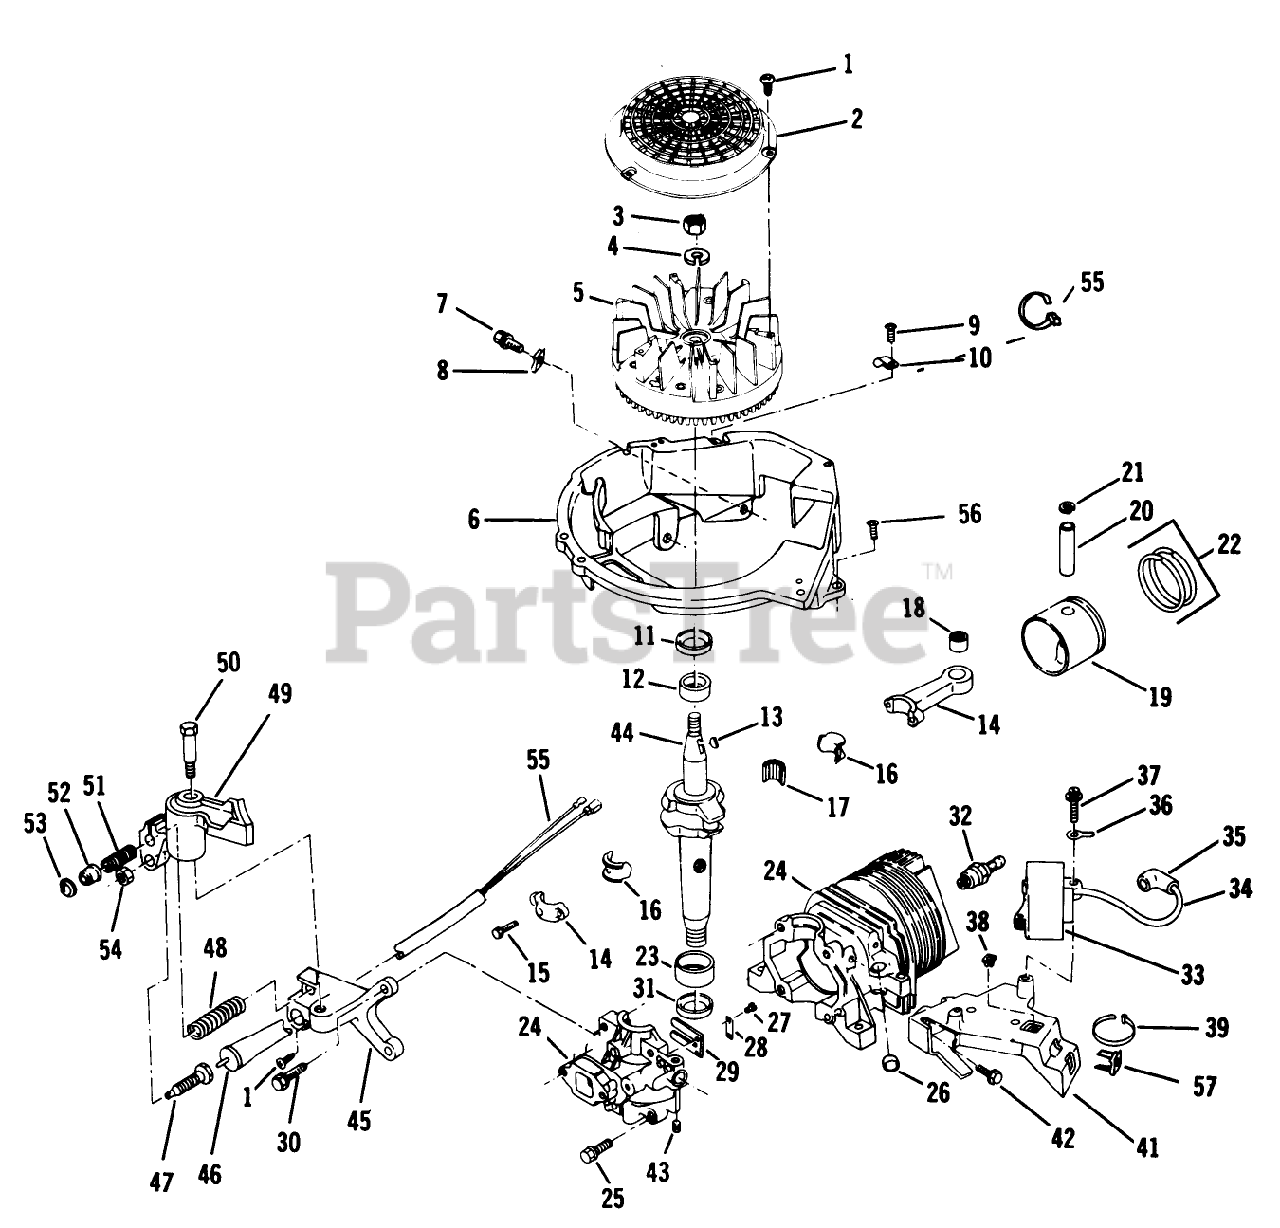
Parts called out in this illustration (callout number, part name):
1	SCREW F
2	SCREEN F'WHEEL S
3	NUT
7	SCREW-SEMS
9	SCREW F
12	BEARING V
13	KEY
15	SCREW-HSH
16	LINER ASM
18	BEARING AY F
21	RING-RETAINING
23	BEARING V
25	SCREW S
26	PLUG-CORE VF
28	PLATE-BACKUP, REED
31	SEAL-OIL
34	HT LEAD&COVER XEV
36	TERMINAL S
38	NUT-CLIP
41	BRACKET S
45	BRACKET-BRAKE F
47	PLUNGER S
48	SPRING-BRAKE
51	SPRING
52	ACTUATOR-LEVER, BRAKE
53	RETAINER S
56	SCREW F
57	NUT-CLIP
57	NUT-SPEED
